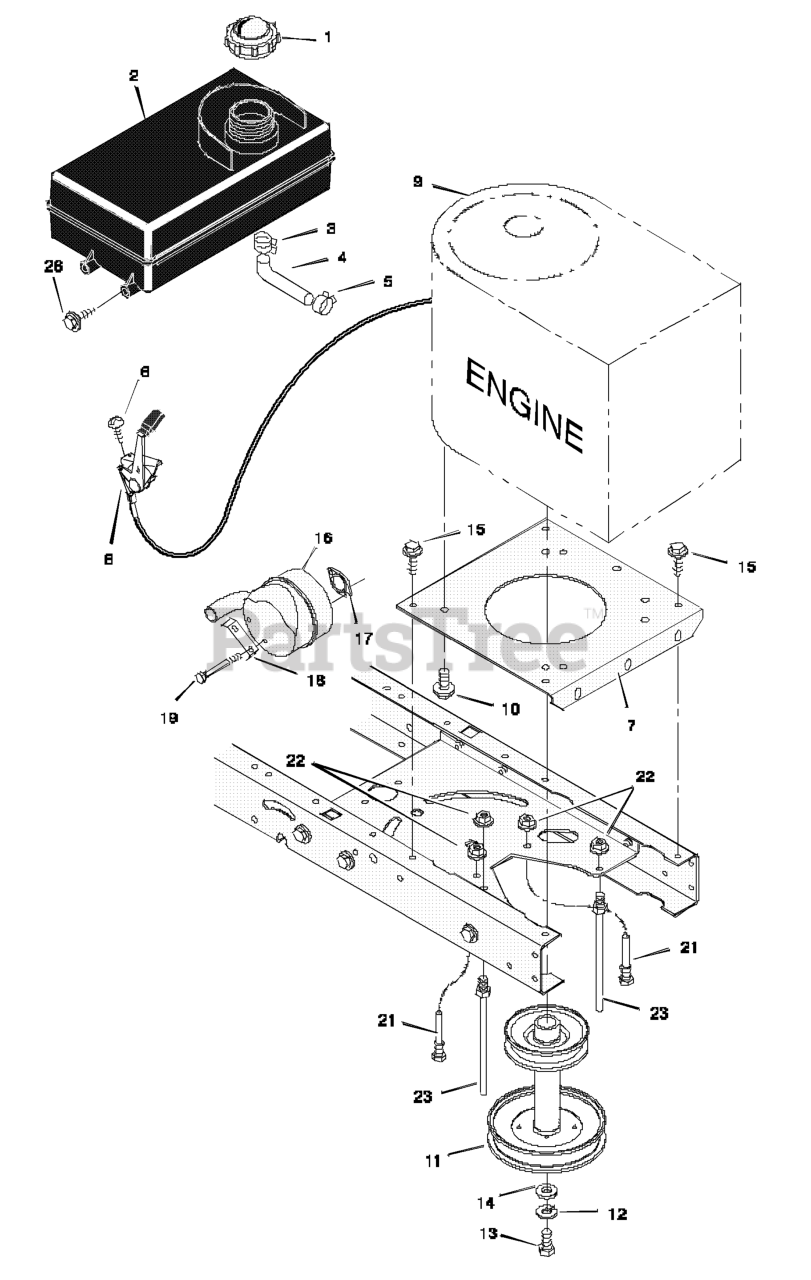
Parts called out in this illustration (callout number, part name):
1	Fuel Cap
2	TANK, Fuel 1.4 Gal.
3	Hose Clamp
4	Fuel Line
5	Hose Clamp
7	Plate, Engine
8	Throttle Control
9	Engine *
10	Bolt, Engine Mount
11	Stack Pulley Assembly
12	Lockwasher
13	Bolt, Hex
16	Muffler
17	GASKET, Exhaust
18	Lock, Screw
21	Guide, Belt
22	Nut, Flange
23	Guide, Belt
